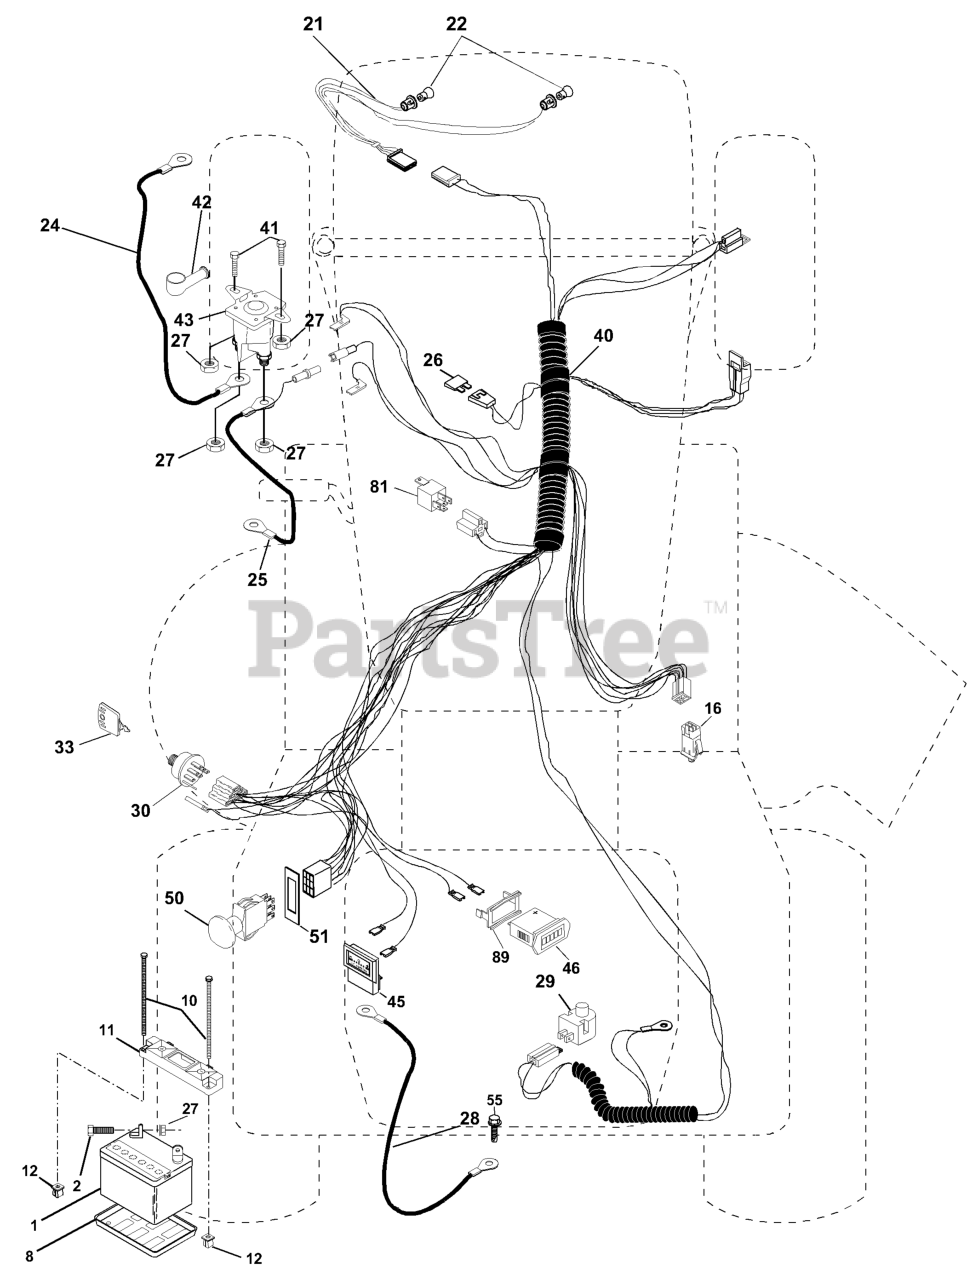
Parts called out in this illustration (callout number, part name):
1	BATTERY 12V .35 AMP
2	BOLT.HEX.1/4.X.3/4.DICHROMATE
8	BATTERY TRAY T
10	BOLT 1/4-20 X 7.5
11	BATTERY HOLDDOWN FRONT MOUNT
12	NUT, PUSH NYLON 1/4" BATTERY
16	SWITCH INTERLOCK
24	BATTERY CABLE GT
25	CABLE BATTERY 6 GA 22" W/16W
26	FUSE 20AMP
27	NUT
28	CABLE GROUND 6 GA 21" 90T BLK
29	PLUNGER SWITCH (COLOR:OLIVE)
30	IGNITION SWITCH
33	KEY MLD GEN DELTA
40	HARNESS, IGNITION
41	BOLT
42	TERMINAL COVER
43	REPL BY 532 1461-54
46	HOUR METER
50	RP.PTO.SWITCH.8 TERMINAL.BLACK
51	FRAME RETAINING RING
55	Screw Thdrol 5/16-18 x 1-1/2 Tyt
81	RELAY.ASSY.T
89	BRACKET SNAP-IN HOURMETER
